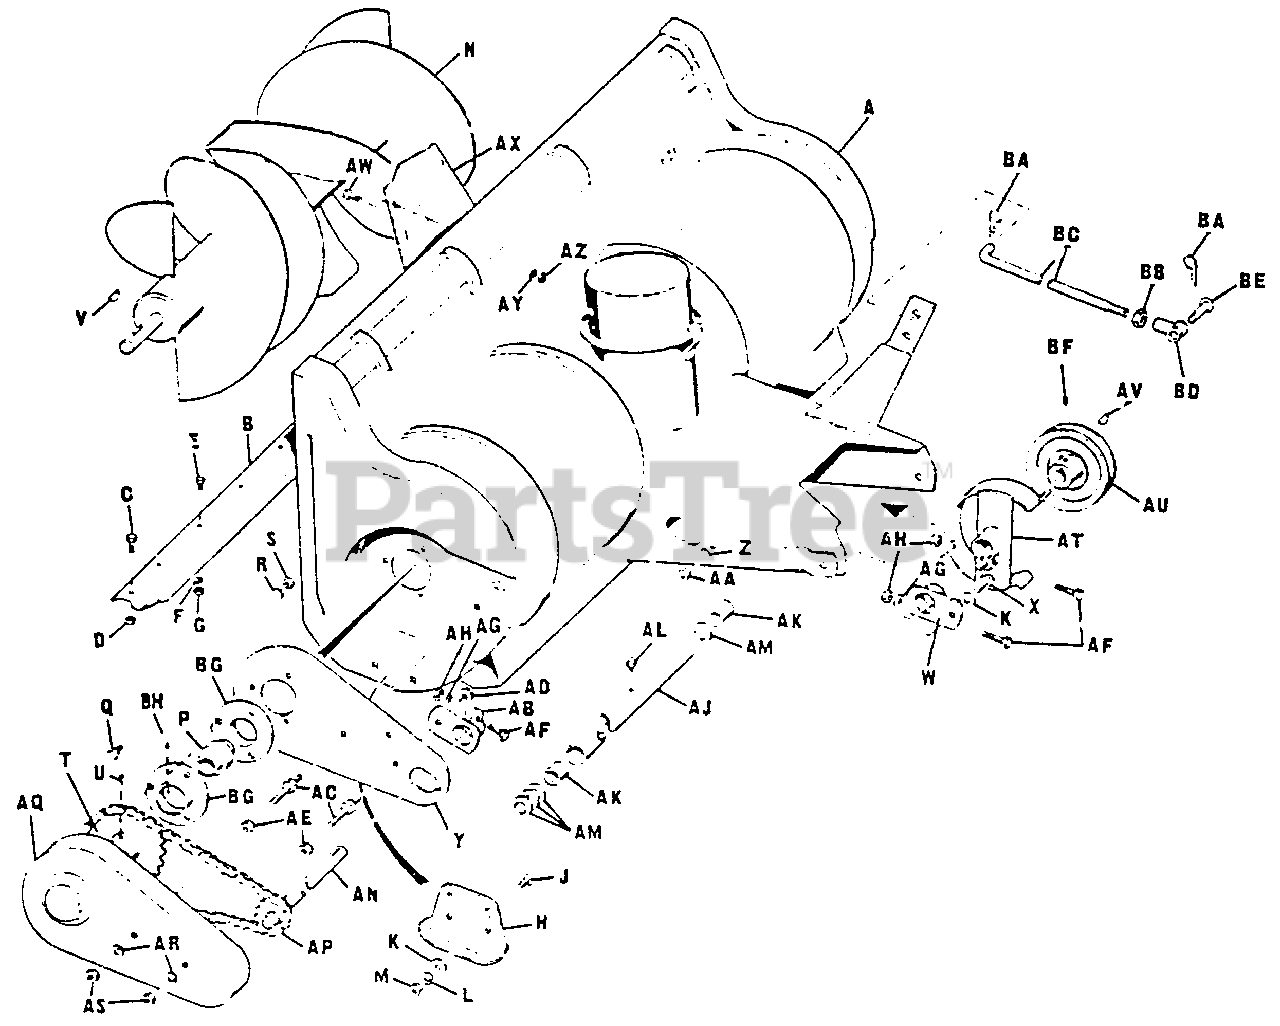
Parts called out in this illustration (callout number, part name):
A	Body Assembly
B	Body Scraper
C	Hex. Cap Screw, 5/16"-l8 x 5/8"
D	Full Lock Hex. Nut, 5/16"-18
E	Hex. Cap Screw, 1/4"-20 x 5/8"
F	Lock Washer, 1/4"
G	Full Hex. Nut, 1/4"-20
J	Carriage Bolt, 3/8"-16 x 3/4"
K	Plain Washer, 3/8"
L	Lock Washer, 3/8"
M	Full Hex. Nut, 3/8"-16
N	Rotor Assembly
P	Bearing Cartridge
Q	Hex. Cap Screw, 5/16"-18 x 3/4"
R	Lock Washer, 5/16"
S	Full Hex. Nut, 5/16"-18
T	Rotor Sprocket
U	Set Screw, 5/16"-18 x 5/16"
W	Support Assembly Clamp
X	Hex. Cap Screw, 3/8"-1 x 1"
Y	Side Plate
Z	Lock Washer, 3/8 "
AA	Full Hex. Nut, 3/8"-16
AB	Support Assembly Clamp
AD	Nut, Flange, 3/8"-16
AE	Full Lock Hex. Nut, 3/8"-16
AF	Hex. Cap Screw, 5/16"-18 x 1-1/2"
AG	Lock Washer, 5/16"
AH	Full Hex. Nut, 5/16"-18
AJ	Bearing Housing
AK	Needle Bearing
AL	Grease Fitting
AN	Shaft Assembly
AQ	Chain Guard
AR	Lock Washer, 3/8"
AS	Full Hex. Nut, 3/8"-16
AT	Belt Guard Assembly
AV	Key, 3/16" Dia. x 3/4"
AW	Hex. Cap Screw, 5/16"-18 x 5/8"
AY	Lock Washer, 5/16"
AZ	Full Hex. Nut, 5/l6"-l8
BA	Spring Clip
BB	Full Hex. Nut, 1/2" x 20
BC	Front Lift Rod
BD	Adjusting End Yoke
BF	Set Screw, 1/4"-28 x 1/4" lg.
BG	Bearing Flange
BH	Set Screw
